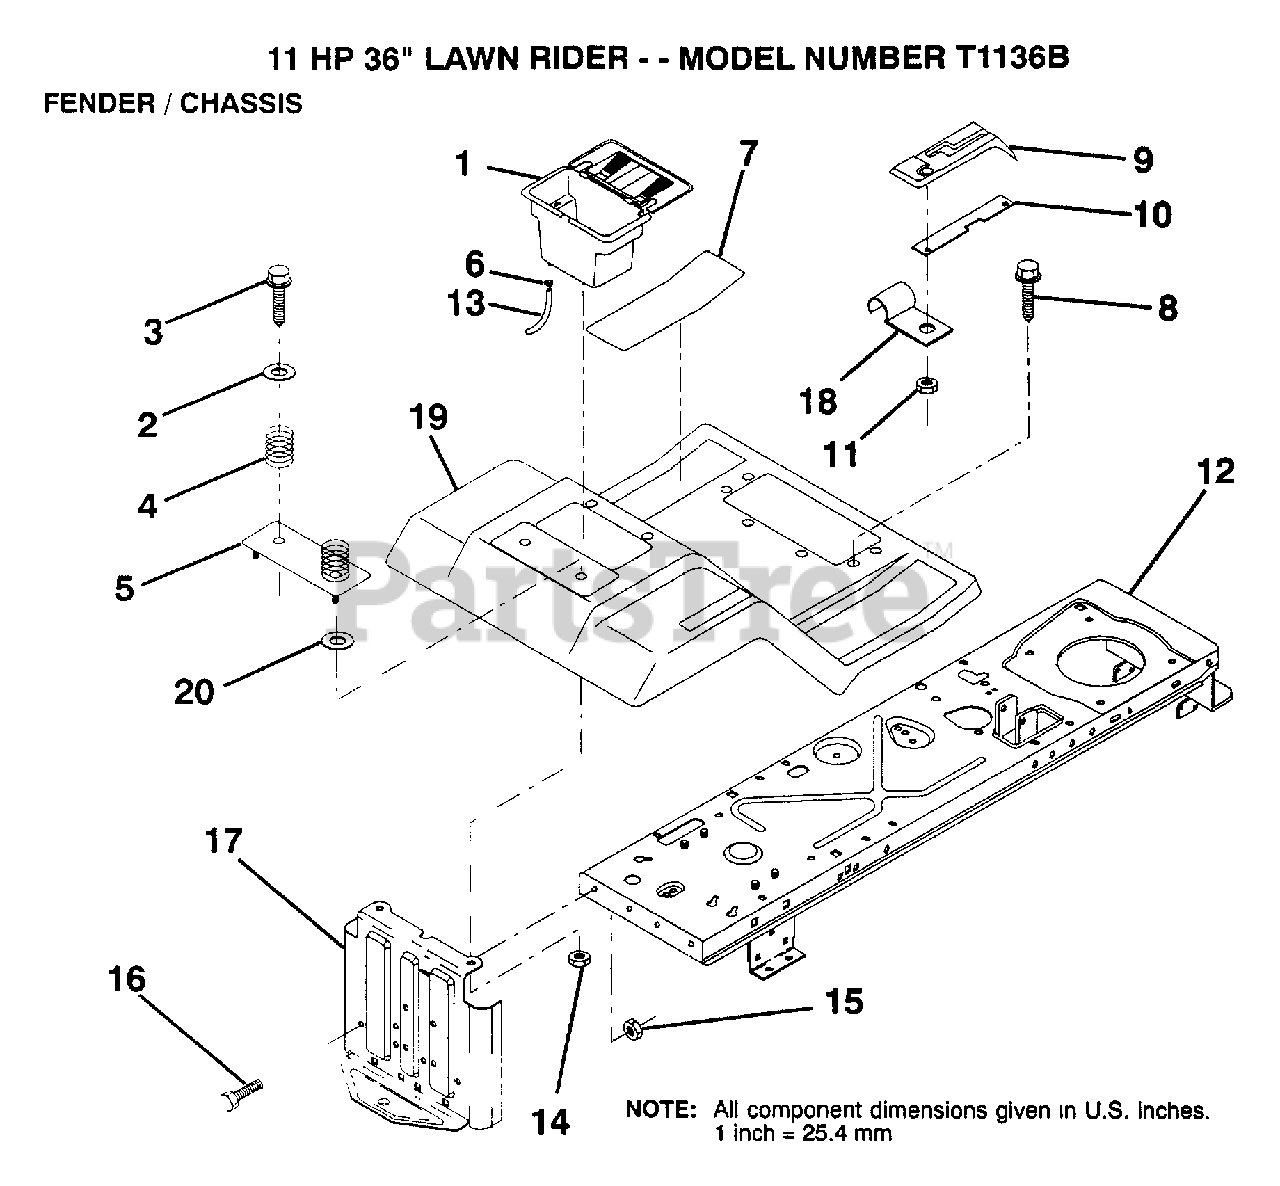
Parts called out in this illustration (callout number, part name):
2	WASHER
3	SCREW
4	SPRING COMPRESSIO
5	"PLATE, BATTERY"
6	HOSE CLAMP T
7	PAD FOOTREST
8	SCREW
9	CONSOLE SHFT 4SP
11	NUT
14	NUT
16	BOLT
17	DRAWBAR
18	"CLIP,INSULATOR"
